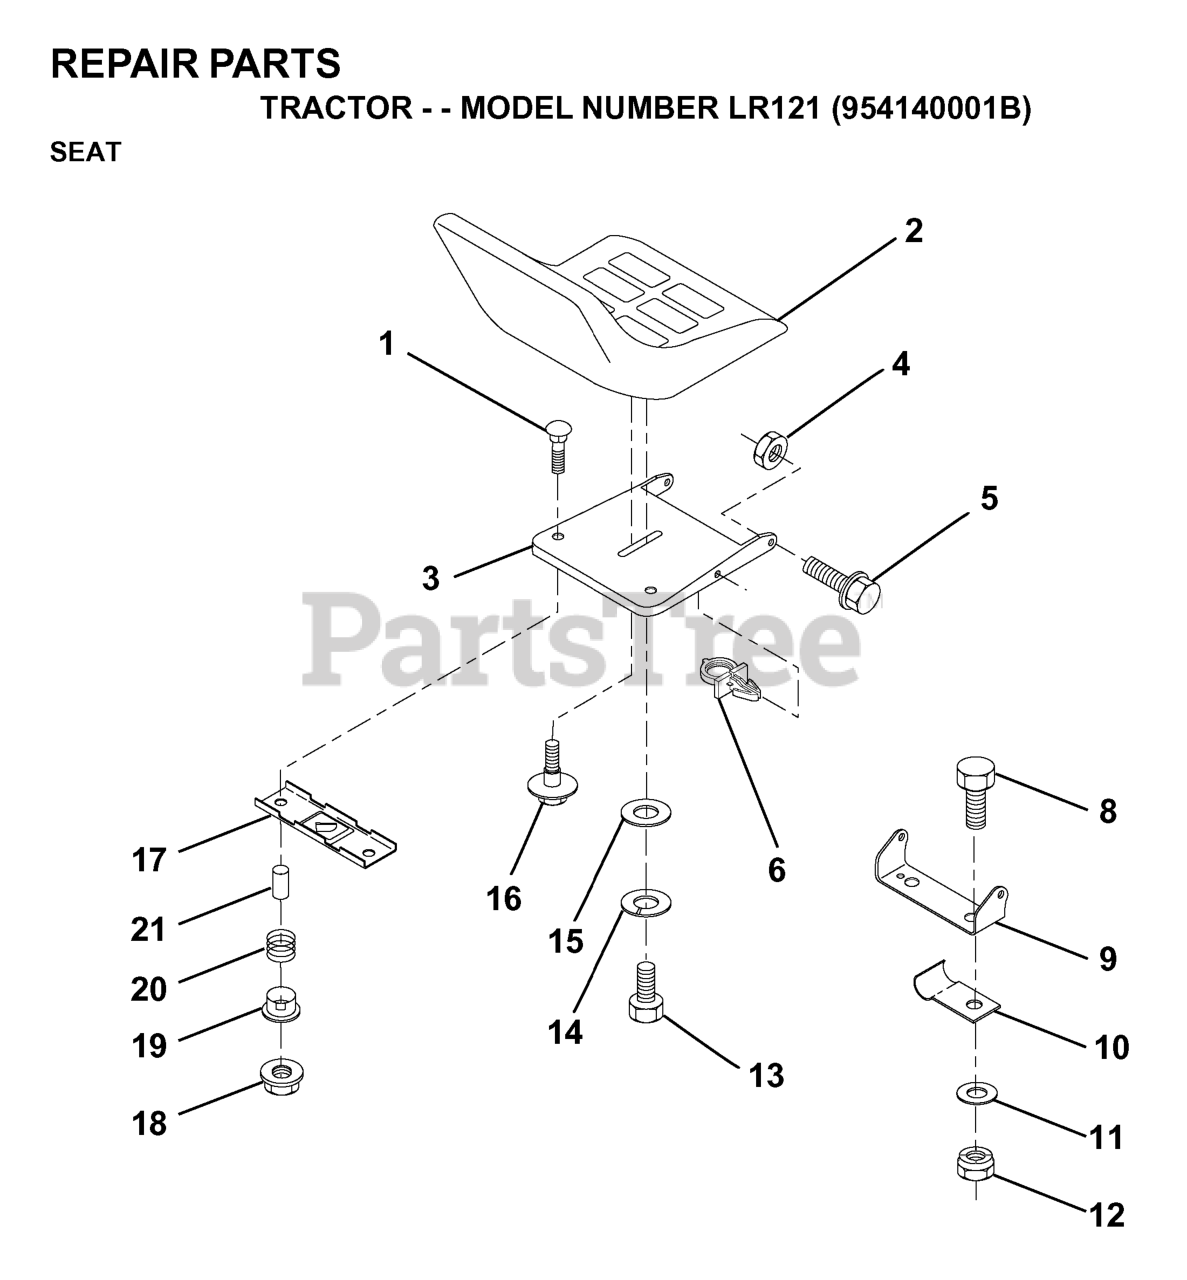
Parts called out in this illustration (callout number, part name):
1	BOLT.ROUND.HEAD.SQUARE.NECK
2	SEAT
3	PAN, SEAT
4	NUT.71038.31-18.HEX.NYLOCK
5	BOLT SHOULDER 5/16-18
8	BOLT
9	SEAT PIVOT BRKT
10	CLIP,INSULATOR
11	WASHER 12/32X2X10GA
12	NUT
13	BOLT
14	LOCKWASHER
16	BOLT,SHOULD
17	BRKT SWITCH
18	NUT T
21	SPACER SPLIT 28X.96
